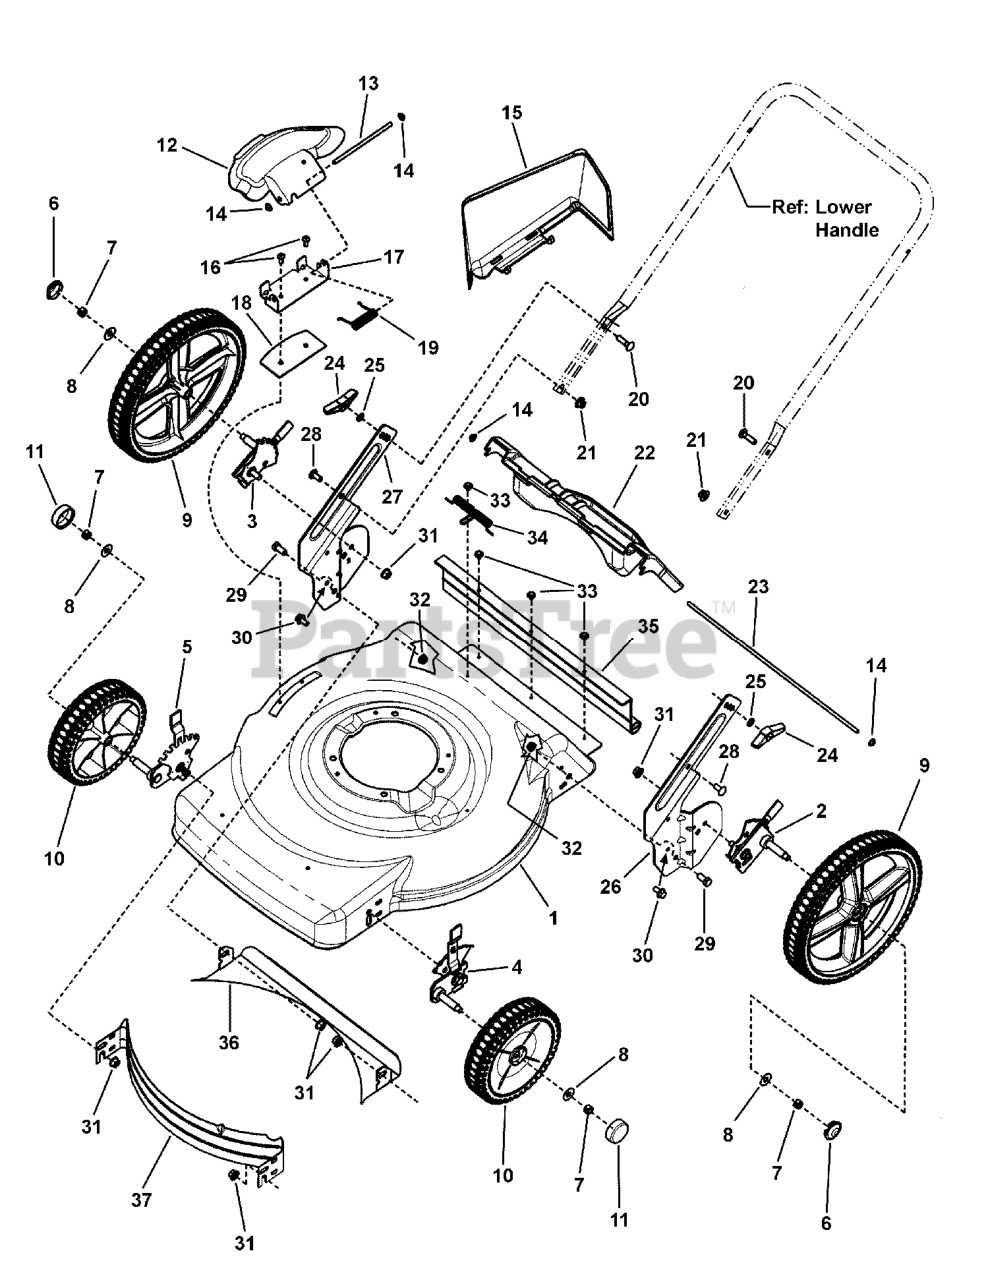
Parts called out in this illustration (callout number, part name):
1	DECK, 22" Walk, Push 3-N-1
2	ASSY, Height-of-Cut, Left Rear, Murray 7 Position
3	ASSY, Height-of-Cut, Right Rear, Murray 7 Position
4	ASSY, Height-of-Cut, Left Front, Murray 7 Position
5	ASSY, Height-of-Cut, Right Front, Murray 7 Position
6	HUBCAP, 12" Wheel, Black
7	NUT, 3/8-16 Hex Center Lock, YZ
8	WASHER, 1" O.D. x .387 I.D. Flat
9	ASSY, Wheel, 12" x 2" Idle, NB, Murray Tread, Pewter
10	ASSY, Wheel, 8"x 2" Idle, NB Murray Tread, Gray
11	HUBCAP, Round, Black
12	COVER, Mulch, Plastic, Black
13	ROD, Chute Pivot (1/4" Dia. x 5.55")
14	PUSHNUT, 1/4"
15	SIDE CHUTE, Plastic, Black
16	SCREW, 1/4-20 x 11/16" Pan Head Self-Tap (Torx)
17	BRACKET, Chute
18	PLATE, Mulch, 22" RB Scott's
19	SPRING, Chute (Torsion)
20	BOLT, 5/16-18 x 1" Square Neck Carriage
21	NUT, 5/16-18 Large Flange Center Lock
22	DOOR, Rear Discharge, 22" Walk Mower
23	ROD, Pivot, Rear Door (1/4" Dia. X 17-1/2")
24	KNOB, 5/16-18 Wing (Black)
25	WASHER, 5/16" Internal Tooth Lock
26	BRACKET, Lower Handle, LH, 22" WBM, Hi-Wheel
27	BRACKET, Lower Handle, RH, 22" WBM, Hi-Wheel
28	SCREW, 3/8-16 x 3/4" Hex Head Cap, GR 5
29	BOLT 5/16-18 x 3/4" Round Head Short Square Neck
30	BOLT, 5/16-18 x 5/8" Hex Flange Lock
31	NUT, 3/8-16 Hex Flange Lock, GR 5
32	NUT, 5/16-18 Flange Lock
33	SCREW, #10-24 x 1/2" Hex Washer Self-Tap (Sems)
34	SPRING, Torsion, Rear Door, 22" Walk Mower
35	GUARD, Rear 22" Hi-Wheel
36	BAFFLE, Rear, 22" Deck
37	BAFFLE, Front, 22" WBM
